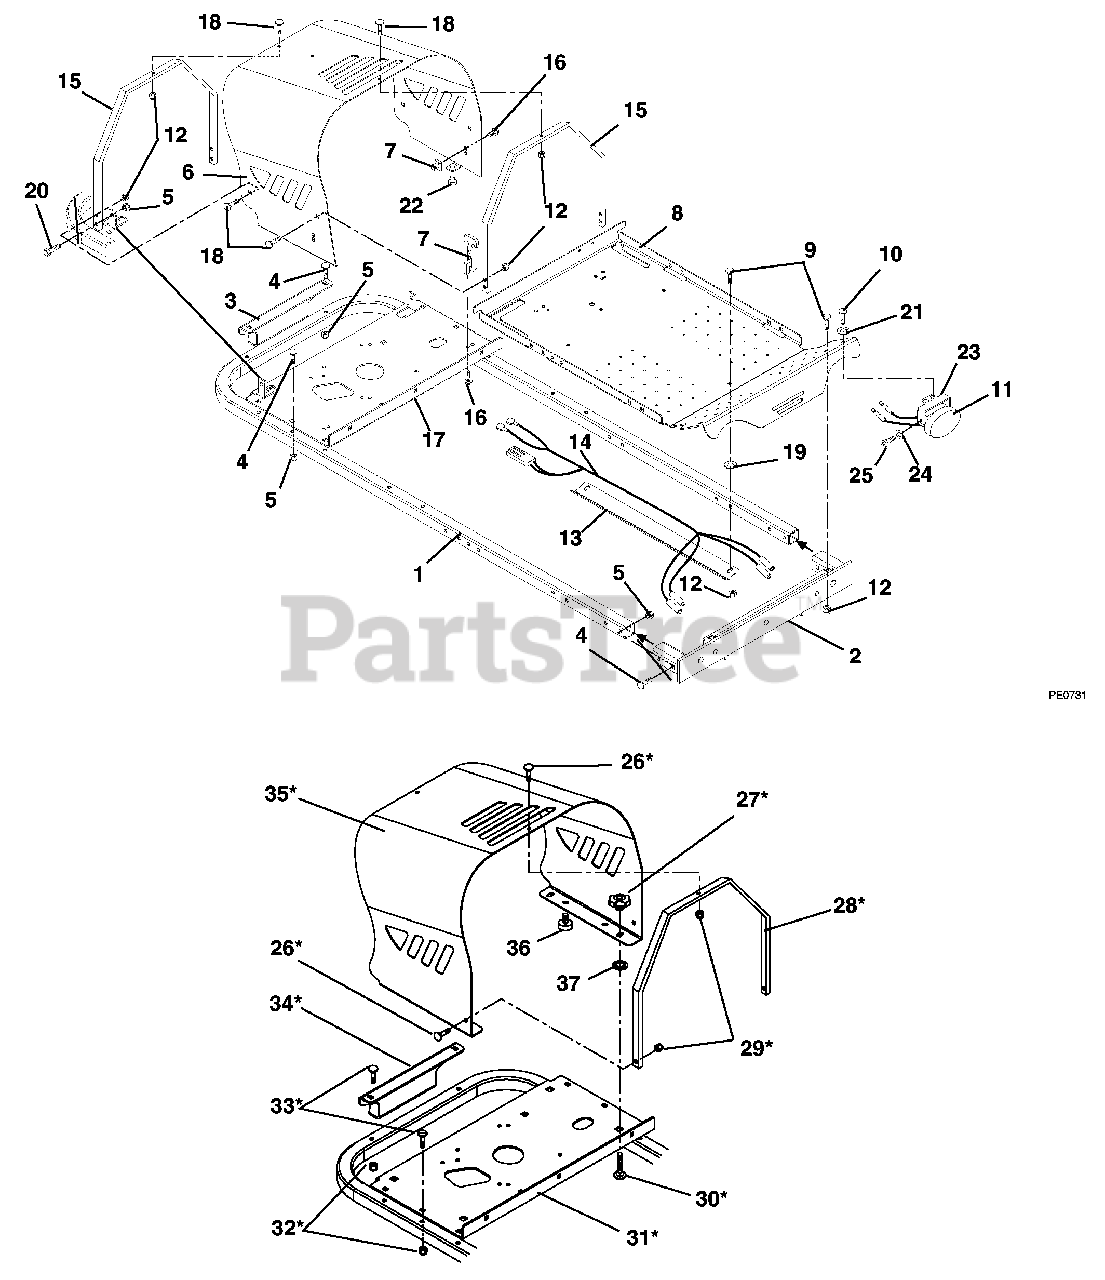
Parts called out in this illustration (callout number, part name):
1	Tube, Frame
2	Weldment, Axle Mount
3	Trailer Hitch
4	Bolt, Round Head Square Neck .38-16 x 2.25 Grade 5
5	Nut, Locking Top Flange .38-16
6	Hood, Zoom
7	Latch, Rubber
8	Footrest
9	Bolt, Round Head Square Neck .31-18 x .75 Grade 5
10	Screw-Cap Button Head .31-18 x .50 Grade 5
11	Light Kit, ZoomXL/ ZTXL
12	Nut, Locking Top Flange .31-18
13	Bracket, Harness
14	Harness, Light
15	Brace, Hood
16	Screw-Machine 10-24 x .50 Hex Washer Head
17	Plate, Engine
18	Bolt, Round Head Square Neck .31-18 x .62
19	Washer, Flat Steel .38 x .87 x .179
20	Bolt, Shoulder .375-16 x .135
21	Washer, Locking .31 x .078 Regular
22	Button Bumper
23	Bracket, Light
24	Washer, Locking 4MM x 1MM Regular Cone Lock
25	Screw, Socket Head Cap M4 x .07 x 8
26	Bolt, Round Head Square Neck .31-18 x .62
27	Knob, Clamping .31-Nyloc
28	Brace, Hood
29	Nut, Locking Top Flange .31-18
30	Bolt, Round Head Square Neck .31-18 x 1.00 Grade 5
31	Bracket, Engine Mount
32	Nut, Locking Top Flange .38-18
33	Bolt, Round Head Square Neck .38-16 x 2.25 Grade 5
34	Trailer Hitch
35	Hood Zoom
36	Button Bumper
37	Nut, Push .312
